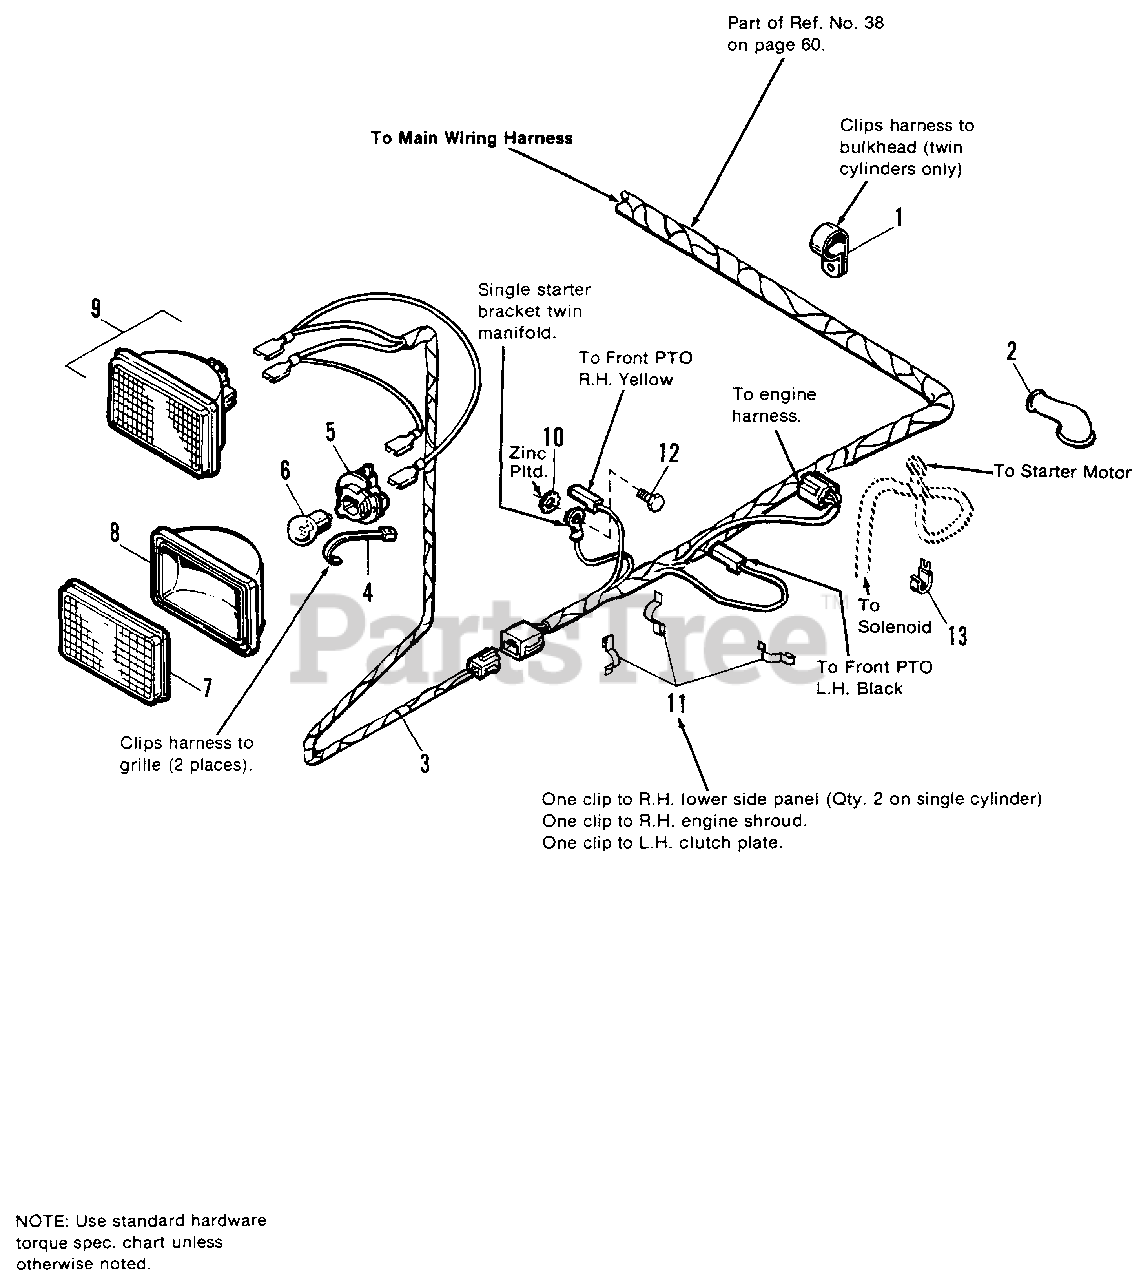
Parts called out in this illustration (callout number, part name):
1	CLAMP (Twin Cylinder Models only)
2	COVER, Terminal
3	HARNESS, Headlight
5	SOCKET, Bulb
6	BULB, 12.8V
7	LENS, Clear
9	HEADLIGHT ASSY. (Incl. Ref. No. 5, 6, 7 & 8)
10	WASHER, Ext. 1/4 Zinc Pltd.
11	CLAMP
12	SCREW, Taptite, 1/4-20 x 3/8 Zinc Pltd.
13	"J" CLAMP (1691250, 1691357 only)
